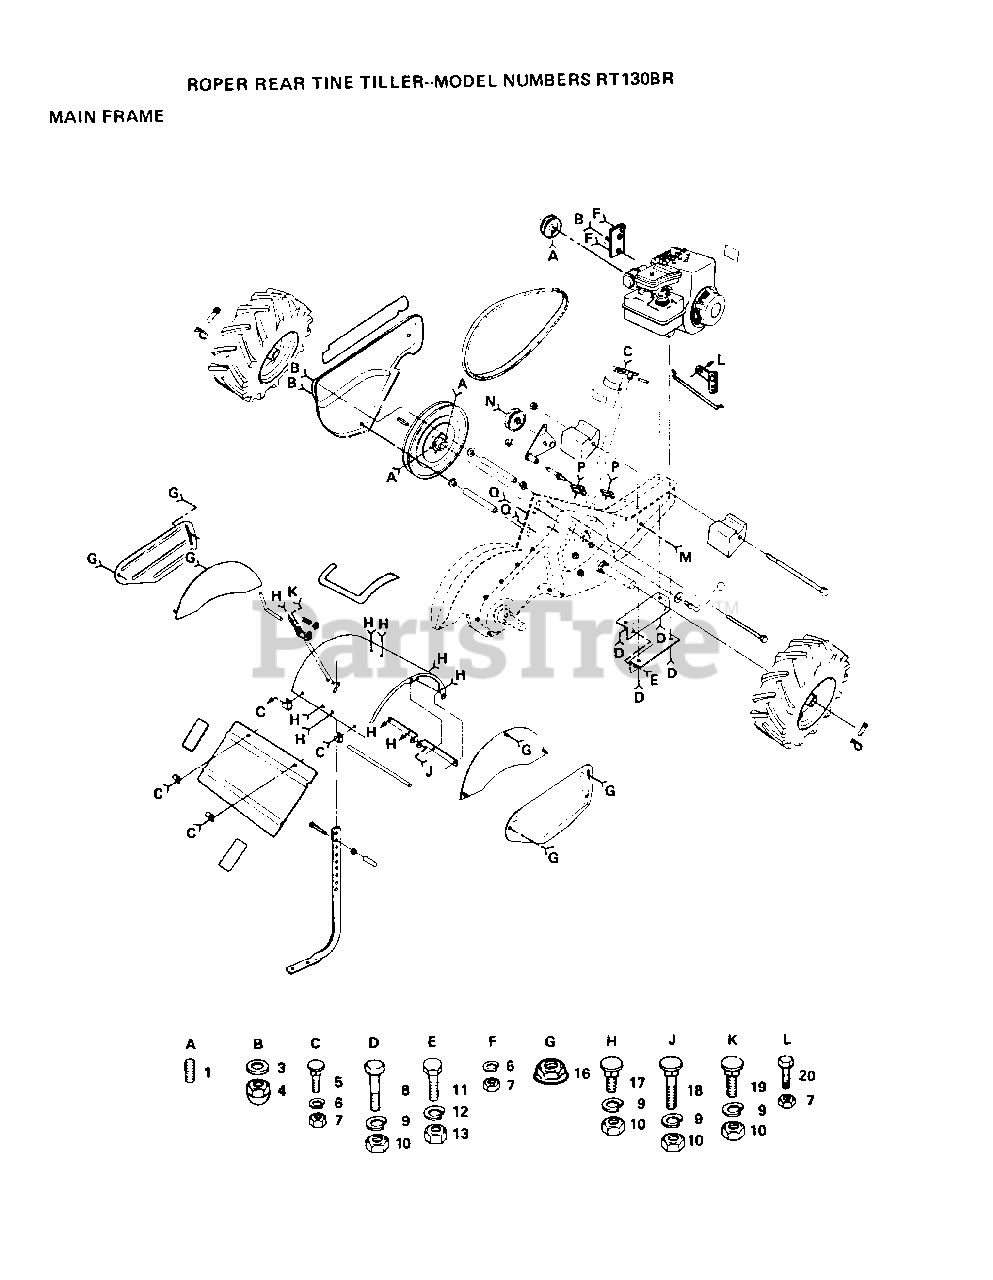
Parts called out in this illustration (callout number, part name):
1	SET SCREW
3	WASHER
4	NUT TI
5	BOLT
6	LOCKWASHER
8	BOLT.HEX.5/16-1.5
9	LOCKWASHER
10	NUT.HEX.5/16-18
11	BOLT
12	LOCKWASHER
13	NUT.HEX.3/8-16UNC
16	NUT
17	BOLT
18	BOLT CRT
19	BOLT
